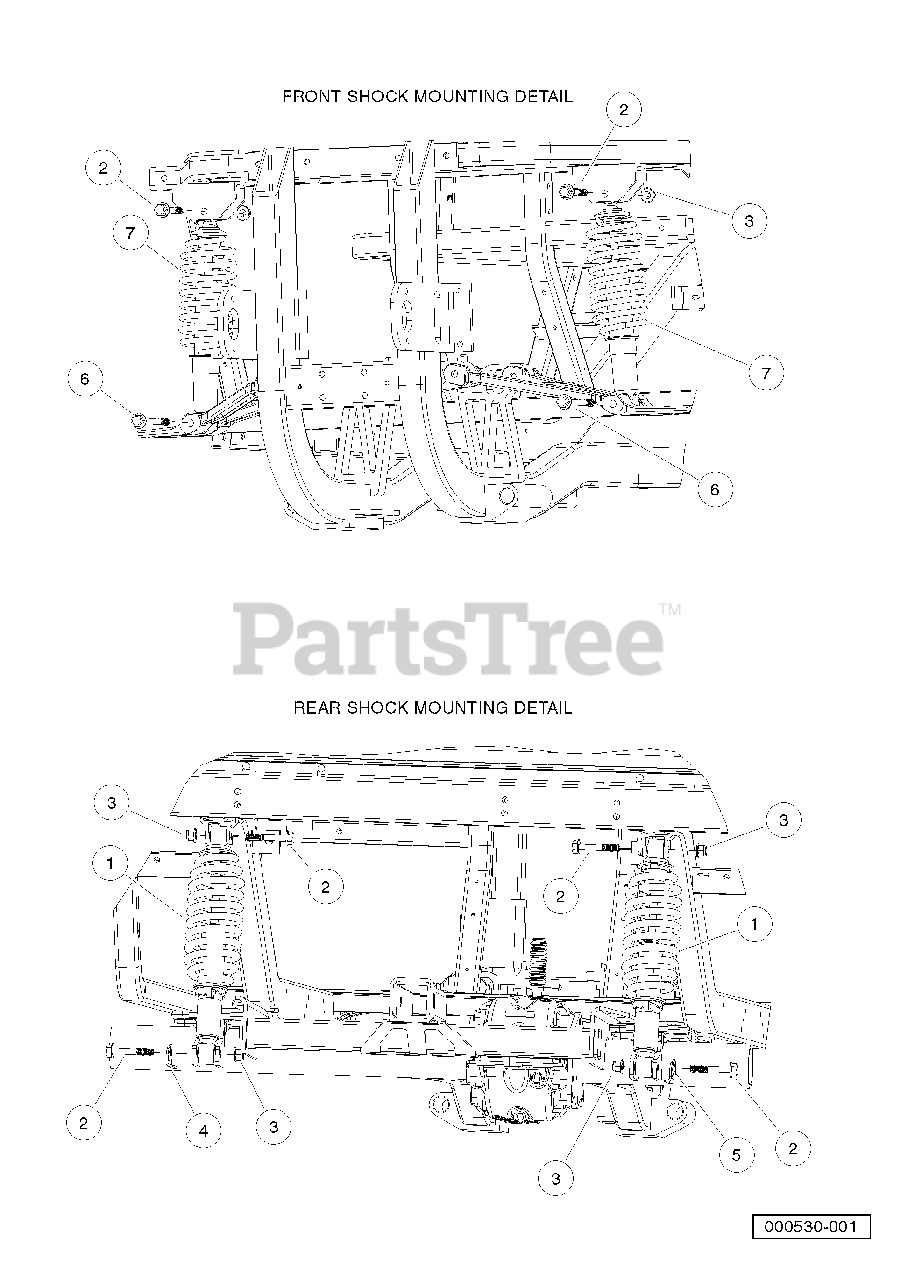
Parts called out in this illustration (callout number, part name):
1	Shock, Coil Over Rear
2	Bolt, Flange Head, M12 X 1.75 X 70
3	Nut Flg, M12x1.75, Nylon Gr 10
4	Brkt, Line, Hyd, Shk Mnt, Drv
5	Brkt, Line, Hyd, Shk Mnt, Pass
6	Bolt Flg, M12x1.75x100, Patch
7	Asm, Coil & Shock, Frt
